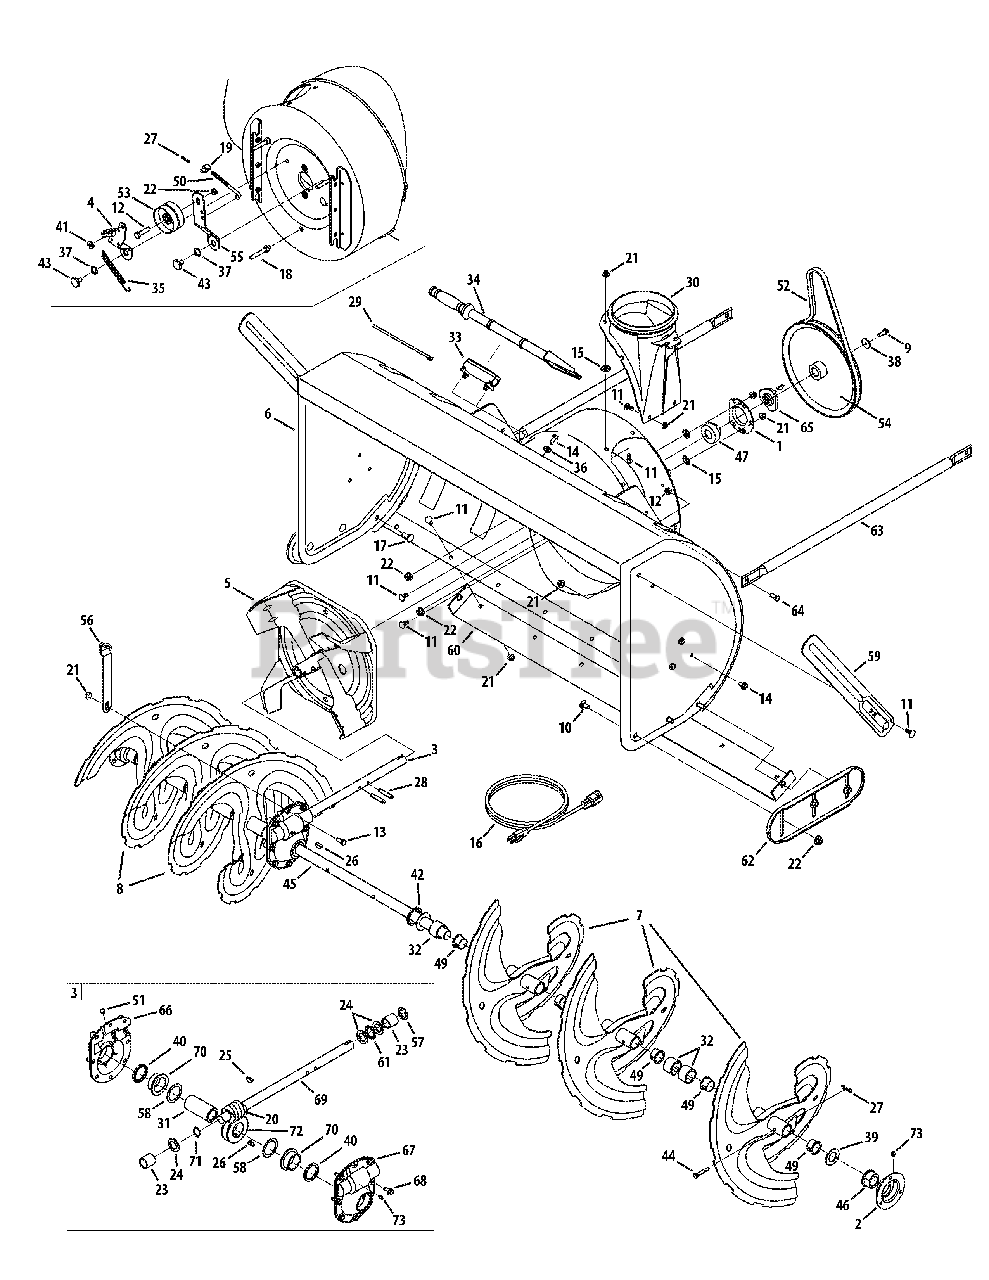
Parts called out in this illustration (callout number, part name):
1	Housing, Bearing
2	Housing, Bearing
3	Gear Box Assembly, Auger
4	Bracket Assy, Auger Brake
5	Impellar, 16"
6	Housing, Auger - 45"
7	Spiral Assy, LH
8	Spiral Assy, RH
9	Screw, 5/16-24 x .875
10	Bolt, Carriage, 3/8-16 x .750
11	Screw, Carriage, 5/16-18 x .75
12	Screw, Hex Cap, 3/8-16 x 1.75
13	Screw, Hex Cap, 5/16-18 x 1.00
14	Screw, 5/16-18 x .750
15	Nut, Push
16	Extension Cord, 110V
17	Bolt, Carriage, 3/8-16 x 1.0
18	Screw, 5/16-18 x .4300
19	Ferrule
20	Gear, Worm, Dbl Thread
21	Nut, Flnge Lk, 5/16-18
22	Nut, Flg Lk, 3/8-16
23	Sleeve
24	Washer, Flat, .88 ID x .38 OD
25	Key, Hi Pro, 3/16 x 3/4
26	Key, Woodruff,1/4 x 3/4
27	Pin, Bowtie Cotter
28	Pin, Spirol, 5/16 x 1.75
29	Tie, Cable
30	Adapter, Chute, 6"
31	Shf, Gear, Worm
32	Spacer, 1.0 x 1.5 x 1
33	Clip, Mounting
34	Tool, Cleanout
35	Spring, Extension
36	Washer, .349 x .879 x .063
37	Washer, .625 x .885 x .015
38	Washer, Flat, .34 x 1.50 x .150
39	Spacer, 1.004 x 1.375 x .25
40	Oil Seal
41	Washer, .344 x .75 x .12
42	Washer, 1.01 x 1.86 x .06
43	Screw, Shoulder, .625 x .17
44	Pin, Shear, .25 x 1.75
45	Axle, Spiral, 45"
46	Bearing, Flange w/Flats
47	Bearing, Self Aligning
49	Bushing, Flange, 1.051 x 1.16
50	Rod, Auger Idler
52	V Belt,4L x 44.60" Long
53	Pulley, Flat Idler, 2.75 OD
54	Pulley, Auger Drive, 10.0
55	Bracket, Auger Idler
56	Bracket, Gear Box Support
57	Seal, Oil
58	Washer, Flat, 1.52 ID x 2.0 OD
59	Drift Cutter
60	Plate, Shave, 45"
61	Brg, Thrust
62	Shoe, Skid
63	Support Tube
64	Screw, 5/16-18 x .75
65	Pulley, Adapter, .75 Dia.
66	Hsg Assy Auger RH (Inc. 40 & 70)
67	Hsg Assy Auger LH (Inc. 40 & 70)
68	Screw, LD, 5/16-18 x .750
69	Shf, Drive, Auger
70	Flange Bearing
71	Ext, Ret, Ring
72	Gear, Worm, LH
73	Lube Fitting, 3/16 #70
